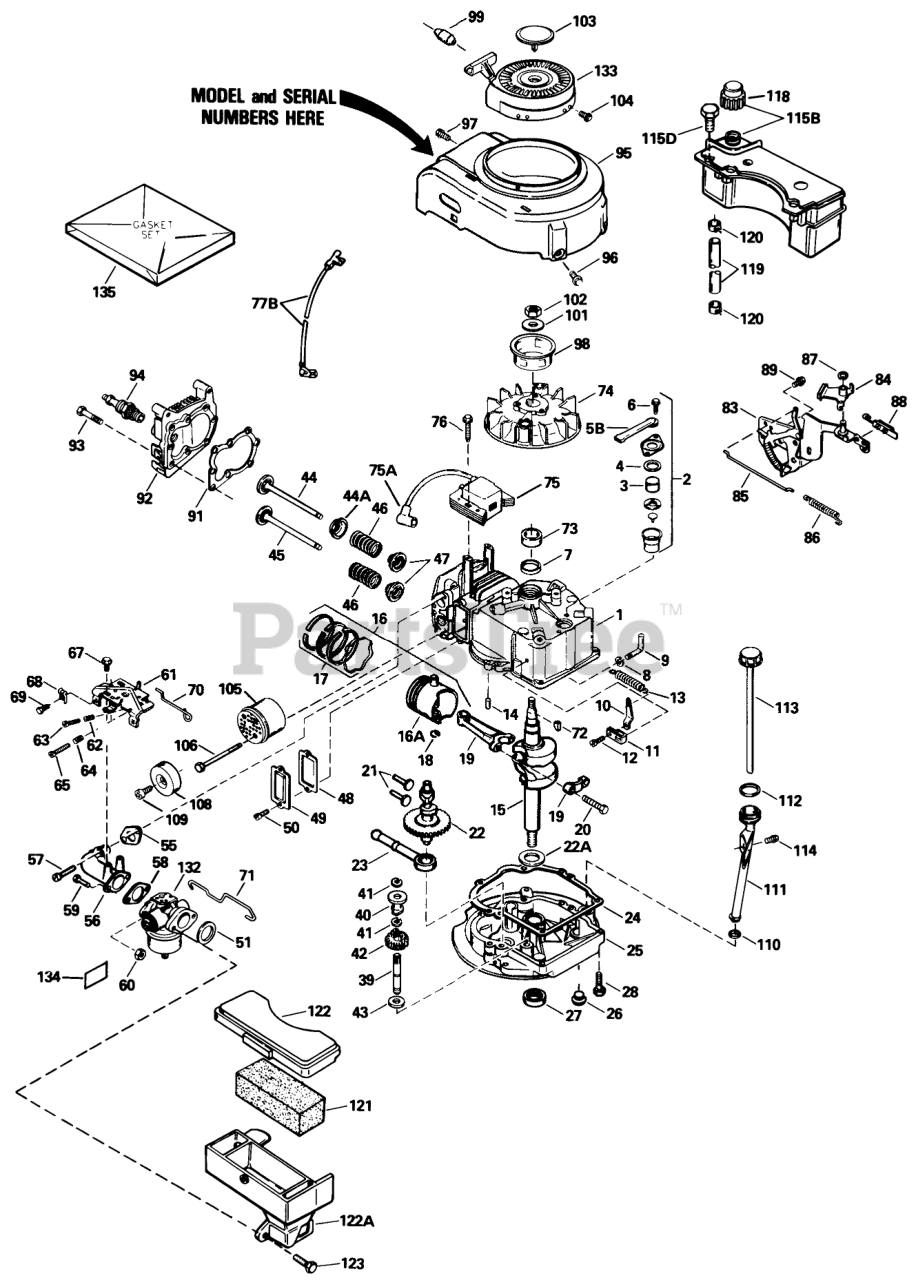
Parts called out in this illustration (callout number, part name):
1	Cylinder Assembly (Incl. Ref. #7 & 14)
2	Breather Assembly (Incl. Ref. #3-6)
3	Element-Breather
4	Gasket-Breather
5B	Tube, Breaker
6	Screw (10-24 x 9/16)
7	Seal-Oil
8	Washer-Flat
9	Rod-Governor (Incl. Ref. #8)
10	Governor Lever
11	Clamp-Lever, Governor
12	Screw
13	Spring Governor
14	Pin-Dowel
15	Crankshaft
16	Piston-Pin & Ring Assy. (Std.)(Incl. Ref. #16A, 17 & 18)
16	Piston-Pin & Ring Assembly (.010 oversize)(Incl. Ref. #16A, 17 & 18)
16	Piston-Pin & Ring Assembly (.020 oversize)(Incl. Ref. #16A, 17 & 18)
16A	Piston & Pin Assembly (Std.)(Incl. Ref. #18)
16A	Piston & Pin Assembly (.010 oversize)(Incl. Ref. #18)
16A	Piston & Pin Assembly (.020 oversize)(Incl. Ref. #18)
17	Ring Set-Piston (Std.)
17	Ring Set, Piston(.0100versize)
17	Ring Set (.020" OS)
18	Ring-Retaining, Piston Pin
19	Rod Assembly-Connecting (Incl. Ref. #20)
20	Bolt-Rod, Connecting
21	Lifter-Valve
22	Camshaft(Mech.Comp. Release)
22A	Washer-Thrust
23	Oil Pump ASM
24	Gasket
25	Flange-Mounting (Incl. Ref. #26, 27 & 39)
26	Plug Oil Drain
27	Seal-Oil
28	Screw (1/4-20 x 1-1/4)
39	Shaft-Governor
40	Spool-Governor
41	Ring-Retaining
42	Gear Assembly-Governor (Incl. Ref. #43)
43	Washer
44	Valve-Intake (Std.)(Incl. Ref. #47)
44	Valve-Intake (1/32" oversize)(Incl. Ref. #47)
44A	Seal Assy., Intake
45	Valve-Exhaust (Std.)(Incl. Ref. #47)
45	Valve-Exhaust (1/32" oversize)(Incl. Ref. #47)
46	Spring-Valve
47	Cap-Valve, Spring
48	Gasket-Cover, Valve
49	Cover-Valve
51	Gasket-Cleaner, Air
55	Gasket-Intake Pipe
56	Pipe-Intake (Incl. Ref. #55)
57	Screw (1/4-20 x 1)
59	Screw (1/4-28 x 7/8)
60	Nut and Lock Washer (1/4-28)
61	Bracket Assembly-Control (Incl. Ref. #62-65)
62	61709/GIL1515A/95-5
63	Screw
64	Spring-Compression
65	Screw
67	Screw (10-24 x 9/16)
68	Conduit
69	Screw (10-32 x 3/8)
70	2035A67 ADD.ASSEMBL
71	Link-Throttle
72	Key-Flywheel
74	Flywheel
75	Solid State
75A	Cover-Spark Plug
76	Screw
77B	Ground Wire
83	Bracket-S.E. Brake
84	Lever-Brake
85	Link-Control
86	Spring-Extension
87	Ring-Retaining
88	Terminal
89	Screw (1/4-20 x 3/8)
91	Gasket-Cylinder Head
92	Head-Cylinder
93	Screw (5/16-18x1-1/2)
94	Spark Plug-Resistor (R J19 L M)
95	Housing-Blower
96	Screw (1/4-20 x 1/2)
97	Screw (10-24 x 9/16)
98	Hub-Starter
99	Retainer-Starter Rope
101	Washer-Belleville
102	Nut-Flywheel
103	Plug Starter
104	Screw, Hex Hd.
105	Muffler Assembly (Incl. Ref. #106)
108	Cover-Muffler
109	Screw (8-32 x 3/8)
111	Oil Fill Tube
113	Dipstick
114	Screw (10-32 x 1/2)
115B	Tank Assembly (Incl. Ref. #118 & 120)
115D	Screw (10-32 x 35/64)
118	Cap-Fuel
119	Line-Fuel
120	Clamp-Line, Fuel
121	Filter-Air Cleaner
122	Cover-Air Cleaner
122A	Body Air cleaner
132	Carburetor (Incl. Ref. #58)
133	Starter-Rewind
134	Decal-Primer
135	Gasket Set (Incl. Items Marked )
